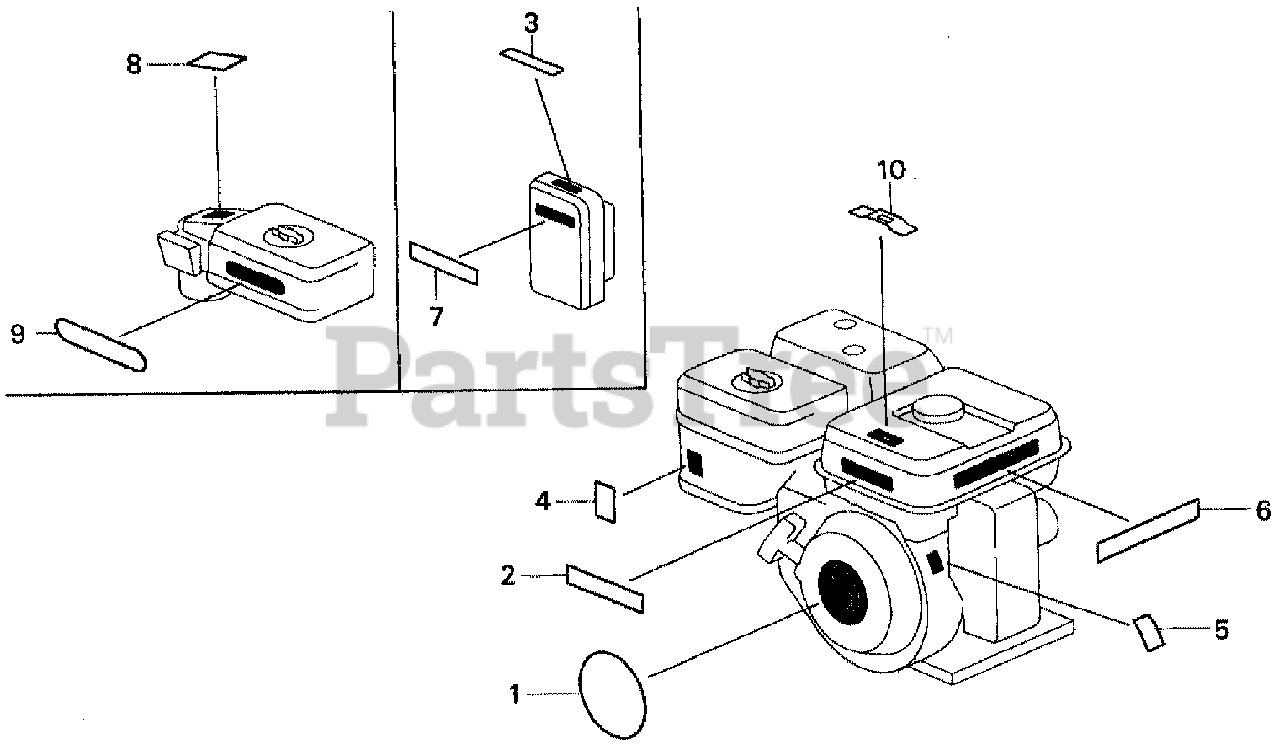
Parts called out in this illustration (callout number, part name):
1	EMBLEM (INTERNAL)
2	LABEL, CAUTION
4	MARK, CHOKE
6	MARK, OIL ALERT (GERMAN)
6	MARK, OIL ALERT (FRENCH)
6	MARK, OIL ALERT (E)
